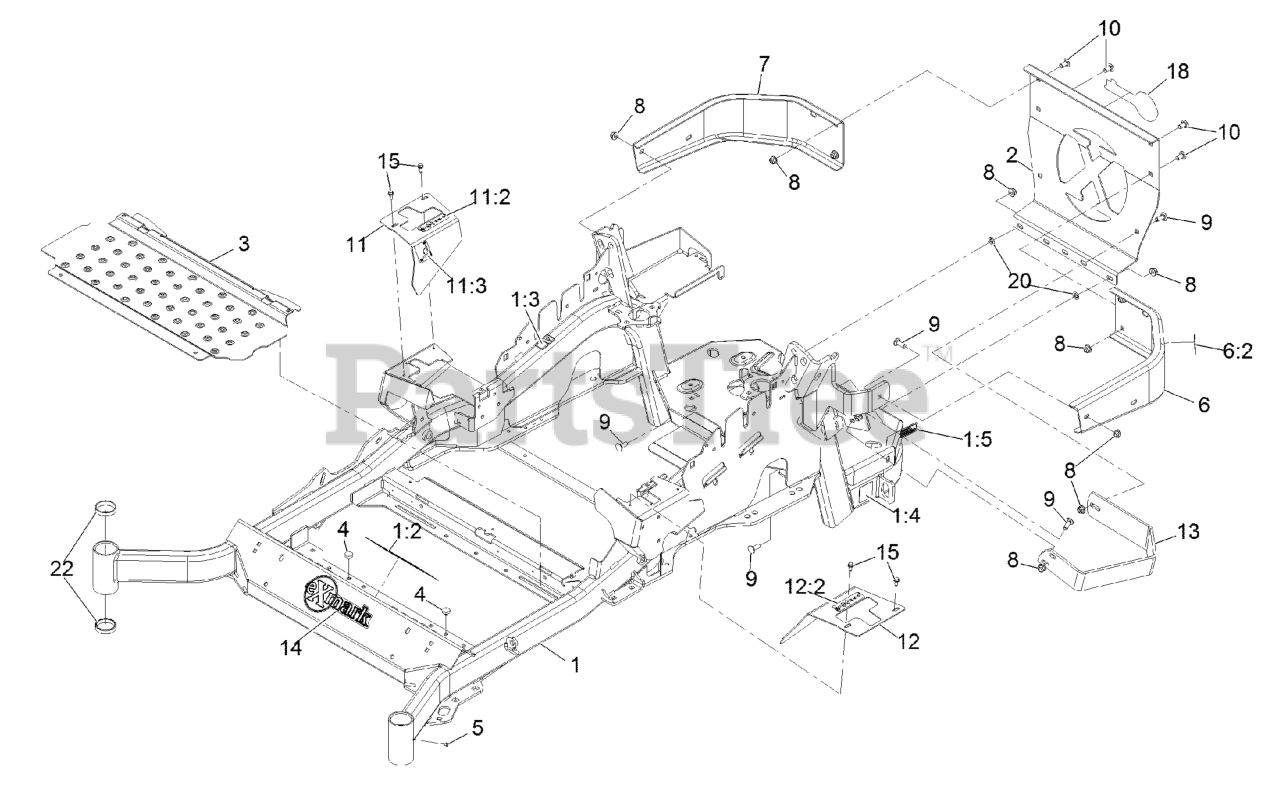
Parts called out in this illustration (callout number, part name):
1	MAINFRAME ASM
1:2	DECAL-DANGER
1:3	DECAL-WARNING
1:4	DECAL-HAZARD, PINCHED FINGER
1:5	DECAL-SPARK ARRESTER
2	PLATE,REAR GUARD
6	LH BUMPER ASM
6:2	DECAL-WARNING
7	BUMPER-RH
8	NUT-HF, NI
9	SCREW-CARR
10	SCREW-CARR
11	RH MOTION CONTROL COVER ASM
11:2	DECAL-CONTROL, MOTION
11:3	DECAL-PARK BRAKE, CE
12	LH MOTION CONTROL COVER ASM
12:2	DECAL-CONTROL, MOTION
13	GUARD-MUFFLER
14	DECAL-EXMARK LOGO
15	SCREW-HWH
18	DECAL-EXMARK LOGO
19	Decal-Patent Ttco.Com
20	NUT-PUSH
21	DECAL-FUEL FILL, CE
22	CUP-BEARING
